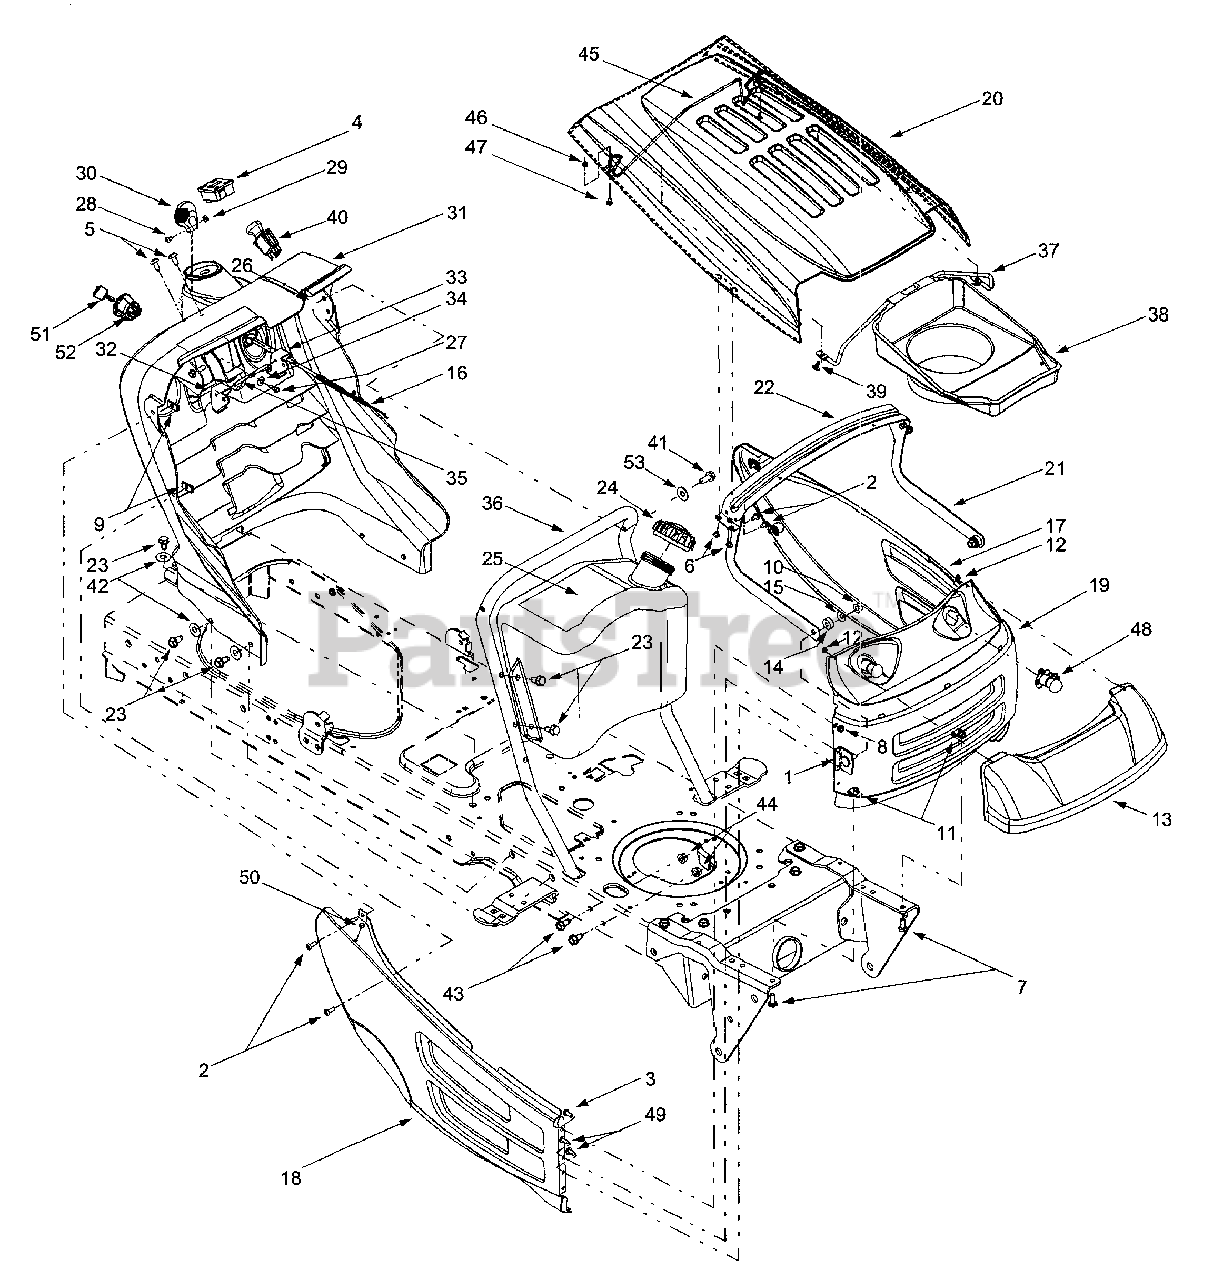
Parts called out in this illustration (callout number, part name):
2	Self-tapping Screw, 1/4-20 x .5
3	Hex Cap Screw, 1/4-20 x .62
4	Systems Indicator Monitor
5	Truss Phillips Screw, 1/4-20 x .625
6	Screw, #10-16 x.5
7	Hex Cap Screw, 5/16-18 x 1.0
8	Hex Sems Nut, 1/4-20
9	U-type Speed Nut, 1/4-20
10	Flange Lock Nut, 3/8-16
11	U-nut, 5/16-18
12	Retainer Nut, 3/8
13	Headlight Lens (8-style)
14	Rubber Washer, .87 x .33
15	Bell Washer, .401 x .87 x .063
16	Choke Knob/Cable
24	Fuel Cap
26	Self-tapping Screw, 1/4-20 x 1.25
27	Self-tapping Screw, 1/4-15 x .75
28	Truss Phillips Screw, #8-32 x .375
29	Hex Nut, #8-32
30	Throttle Control Knob
31	Dash Panel, 8-style
32	Cruise Control Button
33	Parking Brake Button
34	Flat Washer, 9/32 x 1/2 x 1/16
35	Brake/Cruise Pivot Rod
38	Heat Shield
39	Ratchet Clip
40	Electric PTO Switch
41	Self-tapping Screw, 1/4-20 x .75
42	Flat Washer, .349 x 1.0 x .063
43	Screw, 5/16-18 x .875 (Grade 5)
44	Hex Nut, 5/16-18
45	Hood Latch (8-style)
46	Hex Sems Nut, #10-32
47	Machine Screw, #10-24
48	Headlight Assembly
49	Hex Index Washer Screw, 1/4-14 x .0625
50	Rubber Bumper
51	Ignition Key w/ plastic cover
52	Ignition Switch
53	Bell Washer, .265 x .75 x .062
